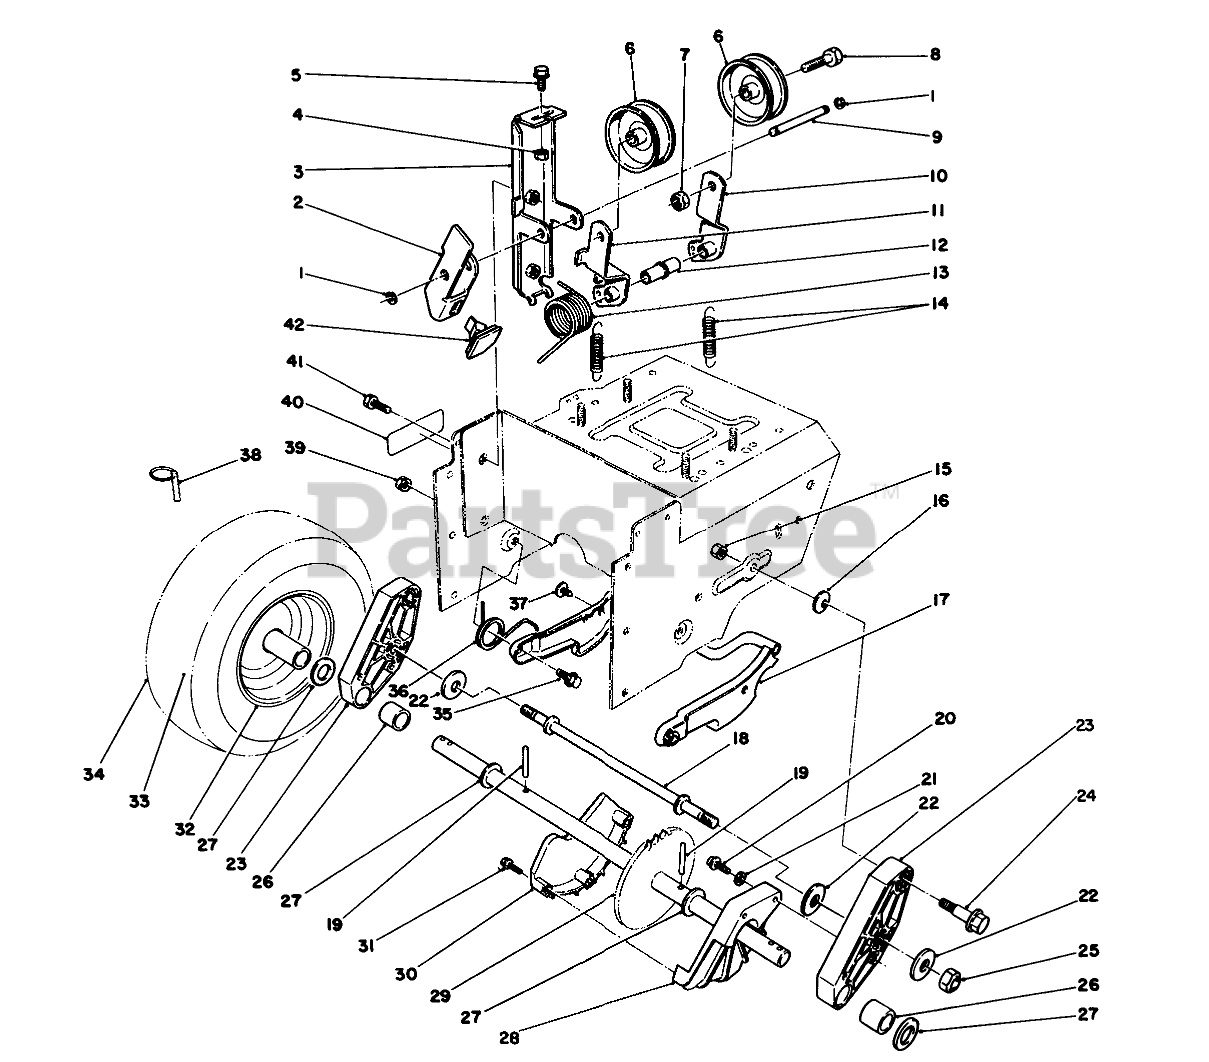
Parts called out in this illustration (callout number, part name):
1	RING-RETAINING
2	ARM-BRAKE
3	IDLER ARM BRACKET ASM
4	NUT-LOCK, NI
5	SCREW-HHF
6	PULLEY-IDLER
7	NUT-LOCK, NI
8	SCREW-HH
9	PIN-IDLER
10	ARM-IDLER, TRACTION
11	ARM-IDLER, IMPELLER
12	BUSHING-IDLER
13	TORSION SPRING
14	SPRING-EXTENSION
15	NUT-LOCK, NI
16	WASHER-SPRING
17	Latch-Arm
18	ROD-LATCH
19	PIN-ROLL, SLOTTED
20	SCREW-HWH
21	WASHER-FLAT
22	WASHER-SUPPORT
23	Pivot Arm Assembly (Incl. Ref. #26)
24	BOLT-SHOULDER
25	NUT-LOCK, NI
26	BUSHING-AXLE
27	WASHER-THRUST
28	GUARD-CHAIN, LH
30	GUARD-CHAIN, RH
31	SCREW-PPH
32	RIM-WHEEL
33	INNER TUBE
35	SCREW-SHOULDER
36	SPRING-LATCH, TORSION
37	FASTENER-PANEL
38	PIN-LYNCH
39	NUT-LOCK, NI
40	DECAL-WARNING
41	SCREW-HHF
42	PAD-BRAKE
